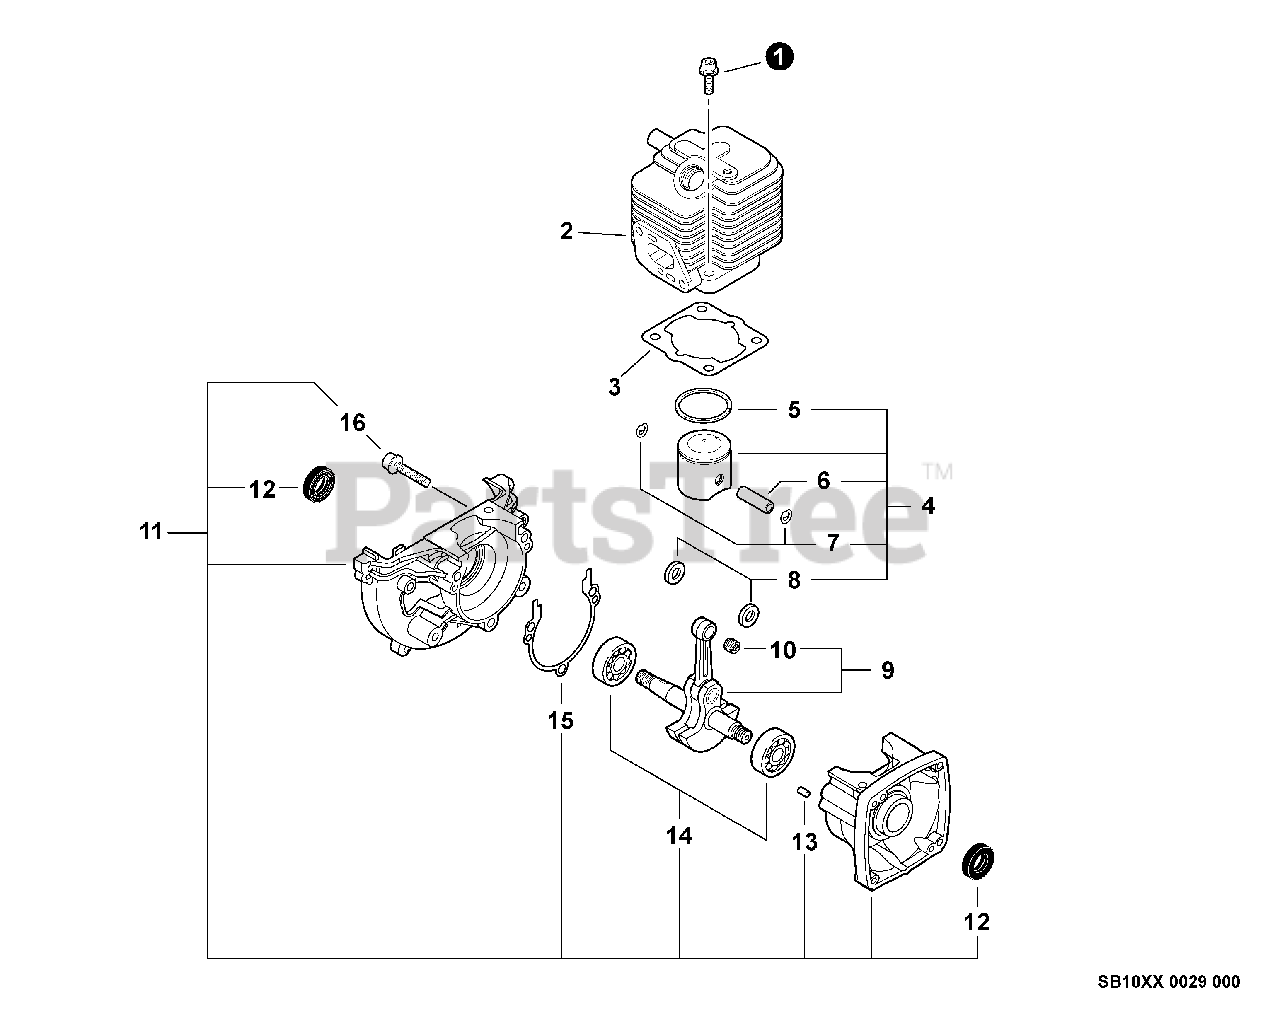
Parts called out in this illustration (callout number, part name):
1	BOLT 5×22
2	CYLINDER
3	GASKET, CYLINDER
4	PISTON KIT
5	RING, PISTON
6	PIN, PISTON 8
7	RING, SNAP
8	WASHER, THRUST
9	CRANKSHAFT ASSY
10	BEARING, NEEDLE 8
11	CRANKCASE KIT
12	SEAL, OIL 12
13	PIN, LOCATING 4
14	BEARING, BALL - 6201 C3
15	GASKET, CRANKCASE
16	BOLT 5×28
